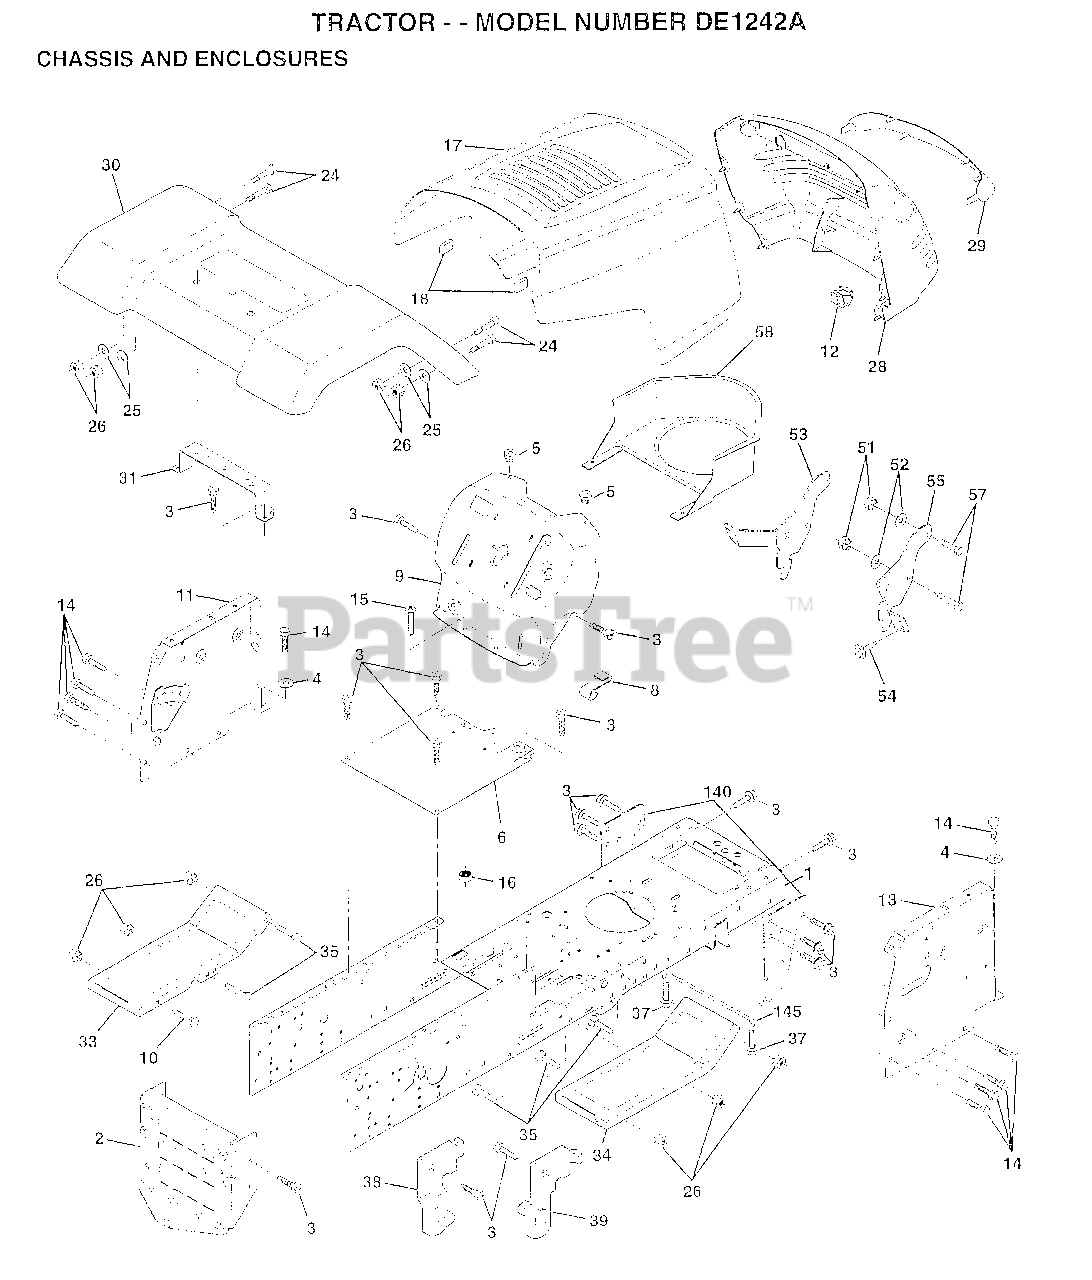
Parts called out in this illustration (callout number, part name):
1	CHASSIS.STAMPING
3	SCREW
4	WASHER
5	BUMPER-HOOD/DASH
6	SADDLE
8	CLIP.RETAINER
9	DASH SILKSCREEN
11	"PANEL-DASH,LH"
12	CLIP.TINNERMAN
14	SCREW LT
15	SCREW
24	BOLT
25	WASHER
26	NUT
28	GRILL
31	BRKT FENDER
33	FOOTREST
35	BOLT
37	SCREW LT
38	BRACKET ASM LH
39	BRACKET ASM RH
51	NUT
52	WASHER
53	BRACKET.GRILLE.LH
54	SCREW.HEX.WS.HD
55	BRACKET.GRILLE.RH
58	AIR DUCT
140	BRKT SUSPENSION
145	"ROD POVOT,CHASSIS"
